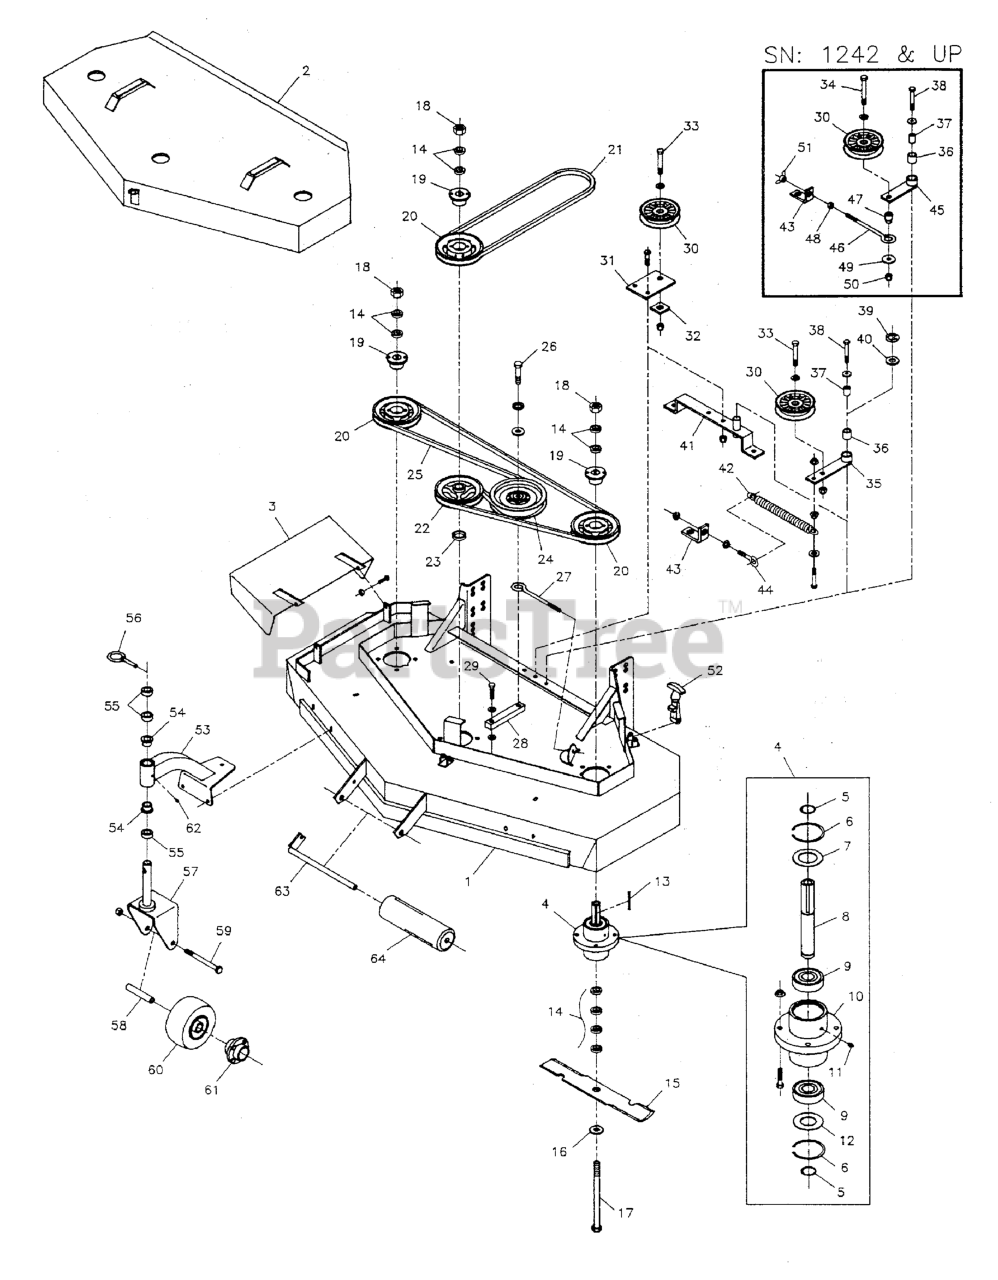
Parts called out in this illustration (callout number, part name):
1	DECK SHELL W/ DECALS, 52, DD52
2	52" DECK GUARD
3	CHUTE, DISCHARGE WELDMENT
4	SPINDLE ASSEMBLY, Complete
5	SNAP RING, External
6	SNAP RING, Internal
7	SPINDLE WASHER, Top
8	SPINDLE SHAFT
9	BEARING
10	SPINDLE HOUSING
11	GREASE FITTING
12	SPINDLE WASHER, Bottom
13	KEY, 1/4 SQ. X 2-1/2
14	SPACER, .63 x 1.06 x .23
15	MOWER BLADE, 18"
16	WASHER, BLADE BOLT, 9/16" F436, CZ
17	BOLT, 5/8-11 x 9-1/2
18	NUT, 5/8-11 Hex
19	BUSHING, Tapered Hub
20	PULLEY, Spindle
21	BELT, Deck Drive
22	SPINDLE PULLEY
23	SPACER, 1.00 X 1.25 X .25
24	PULLEY, Backside Idler
25	BELT, Blade Spindle
26	BOLT, 1/2-20 X 2-1/4 GD5 CZ
27	EYEBOLT, 3/8" x 8"
27	J-BOLT
28	ARM, Idler
28	IDLER ARM
29	BOLT, 7/16-20 X 1-3/4" GD.5
30	PULLEY, Idler
31	BRACKET, Idler Pulley
32	SPACER, Idler Pulley
33	BOLT, 1/2-20 X 2-1/4 GD5 CZ
34	BOLT, 1/2-20 x 3
35	Idler Arm
36	BUSHING, Brass
37	SPACER, .32 x .75 x 1.06
38	BOLT, 5/16-18 x 1-3/4
39	C-CLIP
40	SHIM
41	Idler Mount
42	SPRING, Extension
43	SPRING ANCHOR
44	EYEBOLT
45	ARM, Idler
46	EYEBOLT, 3/8" x 8"
47	INSERT, Bearing Shoulder
48	NUT, 3/8-16 Hex
49	WASHER, 1/2" USS
50	NUT, Hex, Nylon Lock, 1/2-20
51	NUT, 3/8-16 Wing Nylon Lock
52	RUBBER LATCH
53	CASTER MOUNT, Complete
54	BUSHING, FLANGE
55	SPACER, 1.02 x 1.56 x .50
56	PIN, Lynch
57	YOKE, Caster
58	AXLE, Caster Wheel
59	BOLT, 1/2-13 x 5-1/2
60	WHEEL & TIRE ASSEMBLY, White, 9 x 3.5 x 4, Complete
61	Hub Complete (Stamped M)
62	GREASE FITTING
64	ROLLER
